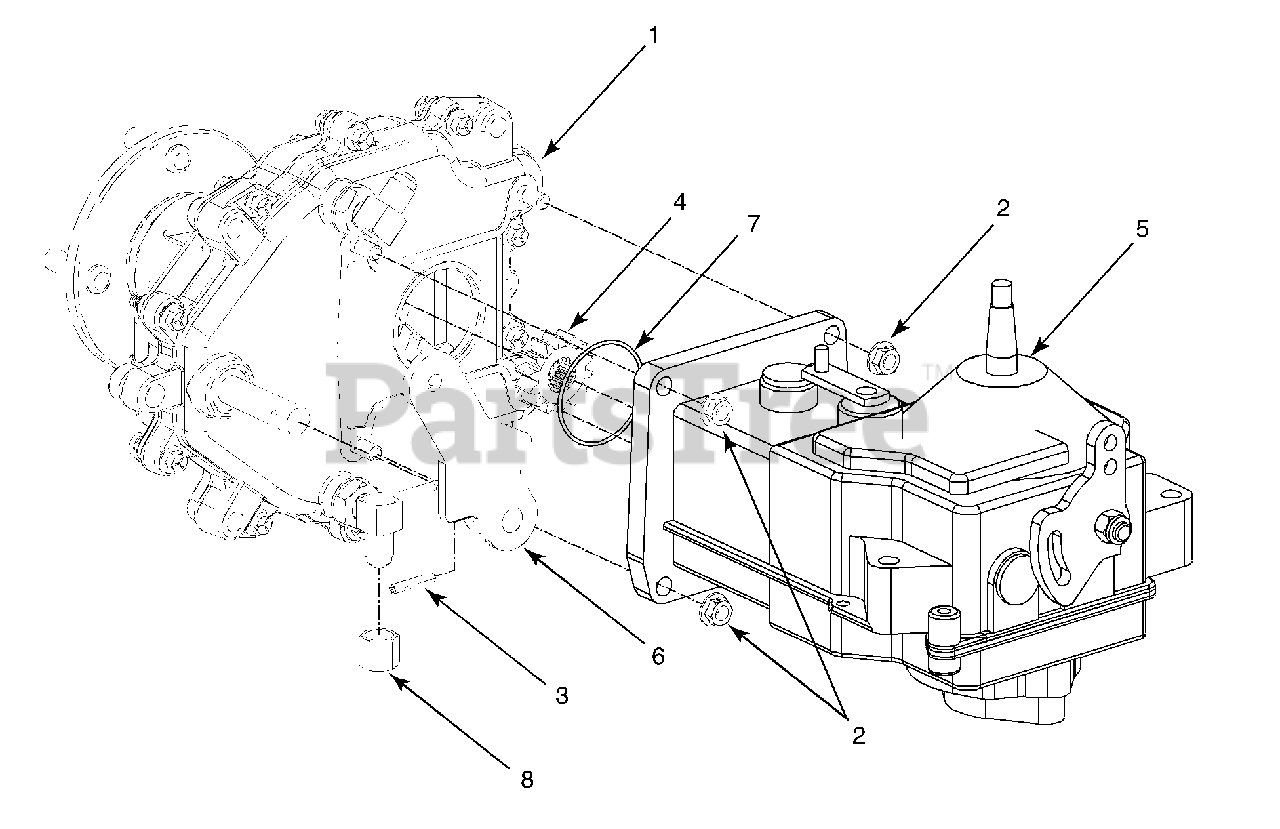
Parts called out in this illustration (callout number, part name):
1	Drive Ass'y, Complete Final
2	Nut, Hex Flange Lock, 5/16-18 GR5
3	Pin, Spirol, 3/16 x 1.25 HD
4	Gear, Spur, 14T
5	Transmission, Hydro: BDR
6	Lever, Park Brake
7	O-Ring, 2.0 Dia.
8	Nut, Cap, 3/8
